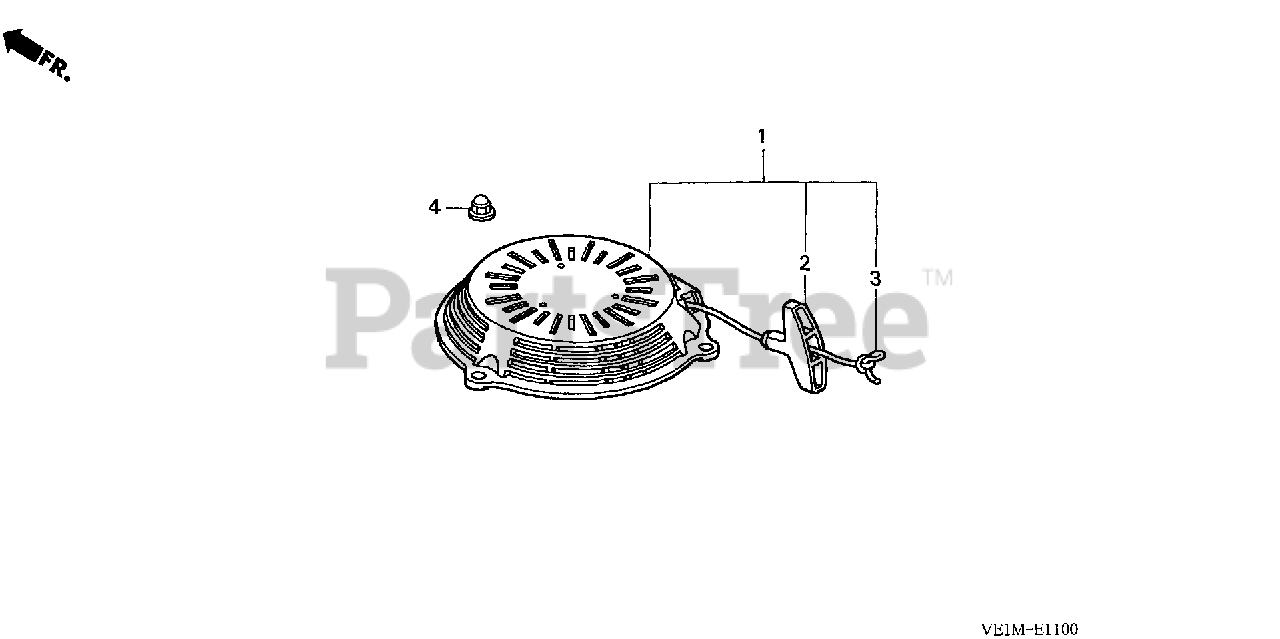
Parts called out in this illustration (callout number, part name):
1	STARTER ASSY., RECOIL *R280* (LONG ROPE) (POWER RED)
2	GRIP, STARTER
3	ROPE, RECOIL STARTER (LONG TYPE)
4	NUT, FLANGE (6MM)
